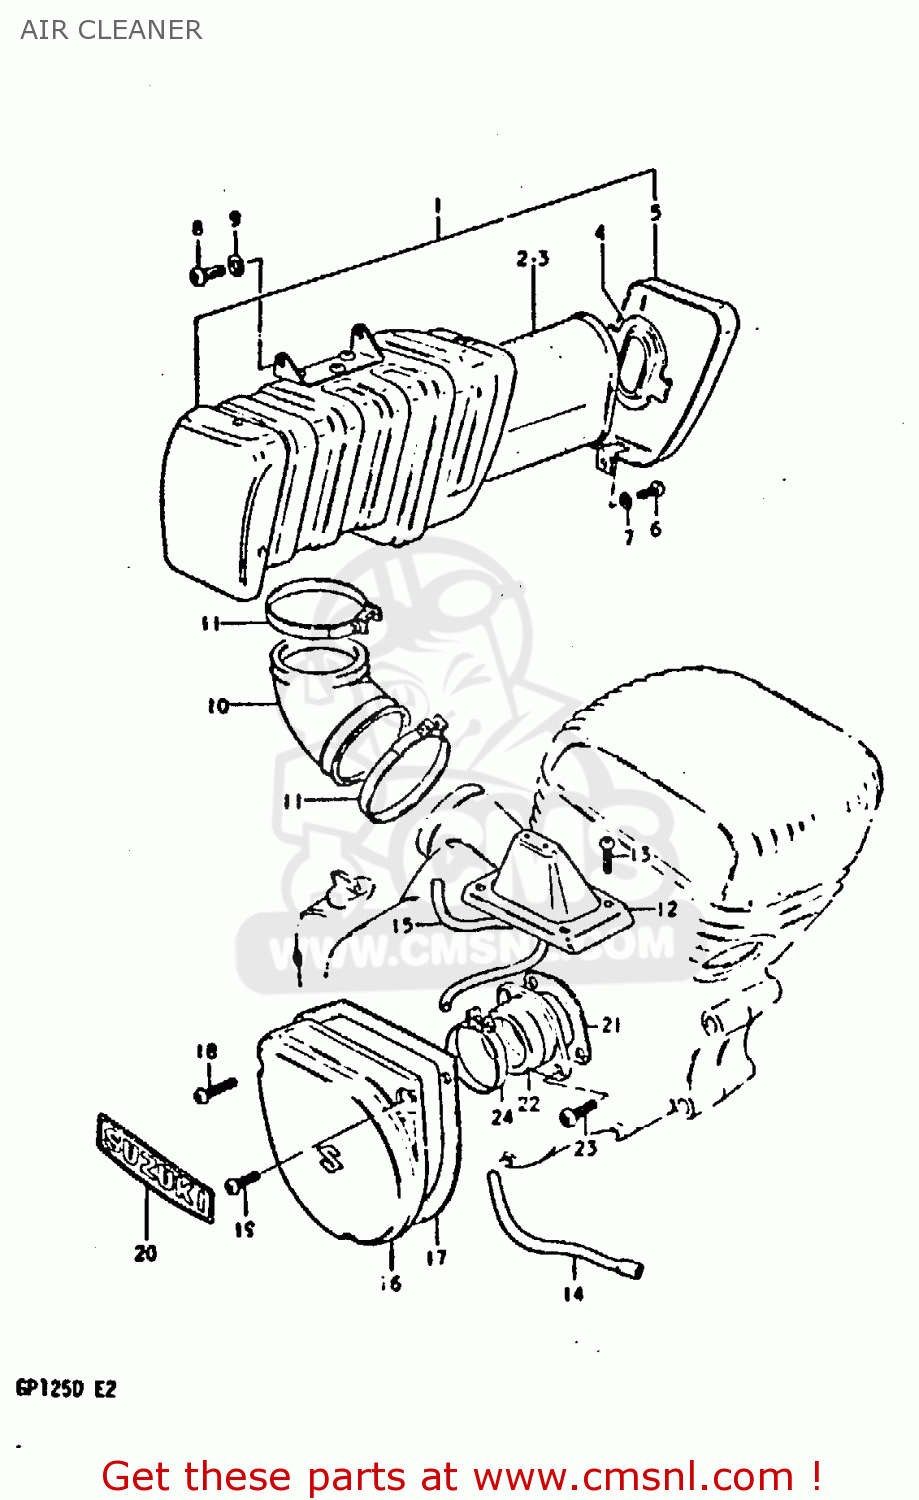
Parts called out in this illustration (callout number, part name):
1	CLEANER ASSY, AIR
2	FILTER ASSY,AIR CLEANER
3	FILTER
4	HOLDER
5	COVER
6	BOLT
7	LOCK WASHER
8	SCREW 6X12
9	WASHER
10	HOSE,CARBURETOR AIR INLET
11	CLAMP
12	CAP,CARBURETOR TOP
13	SCREW
14	HOSE,CARBURETOR AIR VENT
15	HOSE
16	CAP, CARB. INSPECTION
17	GASKET,CARB INSPECTION CAP (NAS)
18	SCREW 5X20
19	SCREW
20	EMBLEM,CARB INSPECTION CAP
21	GASKET,CARBURETOR (NAS)
22	PIPE,INTAKE
23	SCREW
24	CLAMP
